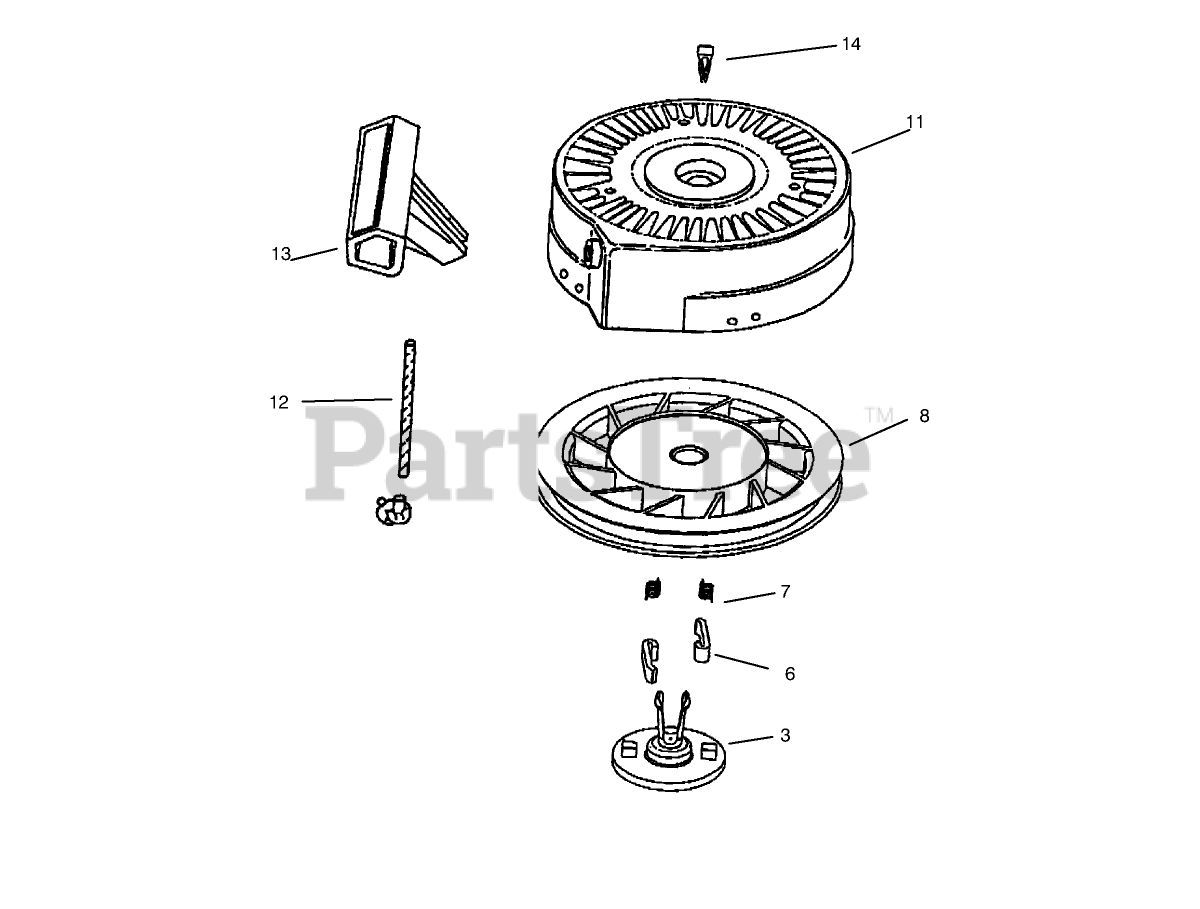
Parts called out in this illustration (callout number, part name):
3	Retainer
6	Dog-Starter
7	Spring-Dog
8	Pulley and Rewind Spring ASM
11	Starter Housing ASM
12	Rope-Starter (98 cut to length)
13	Handle-Starter (STD)
14	Locking Tab
